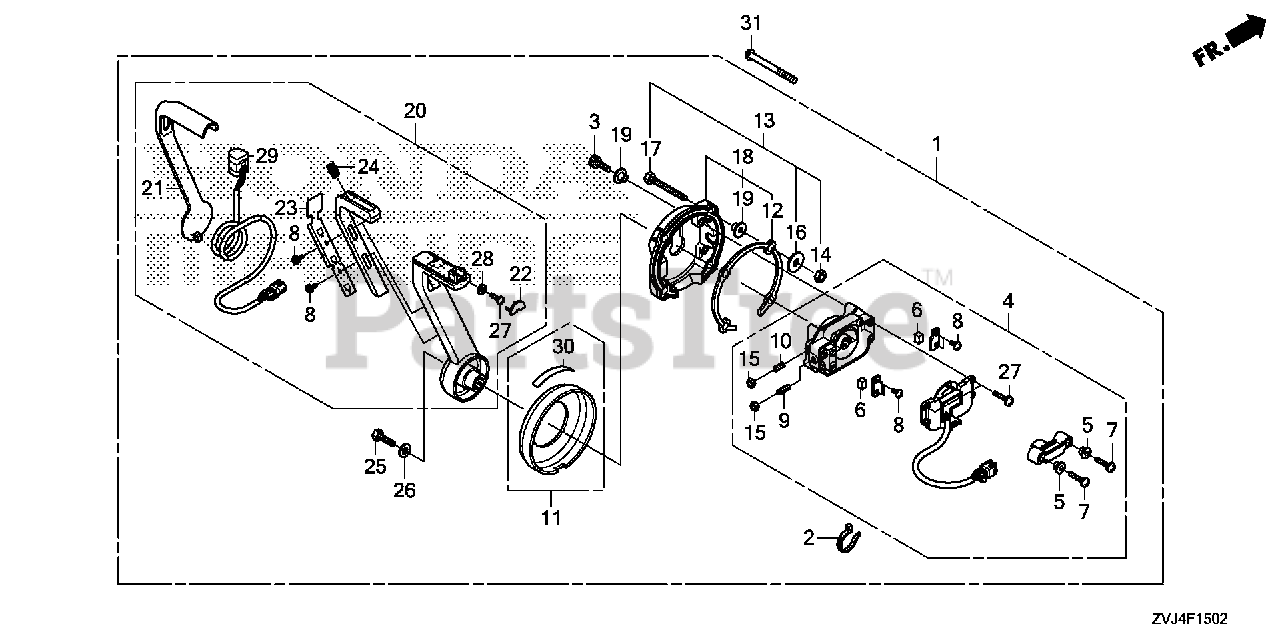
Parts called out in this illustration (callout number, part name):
1	BOX ASSY., REMOTE CONTROL (FLUSH MOUNT)(RH)
2	BAND, NYLON
3	BOLT, SOCKET
4	HOUSING ASSY. (FLUSH MOUNT)
5	COLLAR, STOPPER
6	SHOE, BRAKE
11	COVER ASSY. (FLUSH MOUNT)
12	SHEET, WATERPROOF (FLUSH MOUNT)
13	NUT SET, MOUNTING
14	NUT, NYLON
18	BASE ASSY. (FLUSH MOUNT)
19	COLLAR, BASE
20	LEVER ASSY. (FLUSH MOUNT)
21	PANEL, LEVER (FLUSH MOUNT)
22	CAP, LEVER (FLUSH MOUNT)
23	PLATE, LEVER PANEL
24	SPRING, COIL
29	SWITCH ASSY., POWER TRIM-TILT (FLUSH MOUNT)
30	MARK, FLUSH MOUNT
31	SCREW, PAN (5X65)
